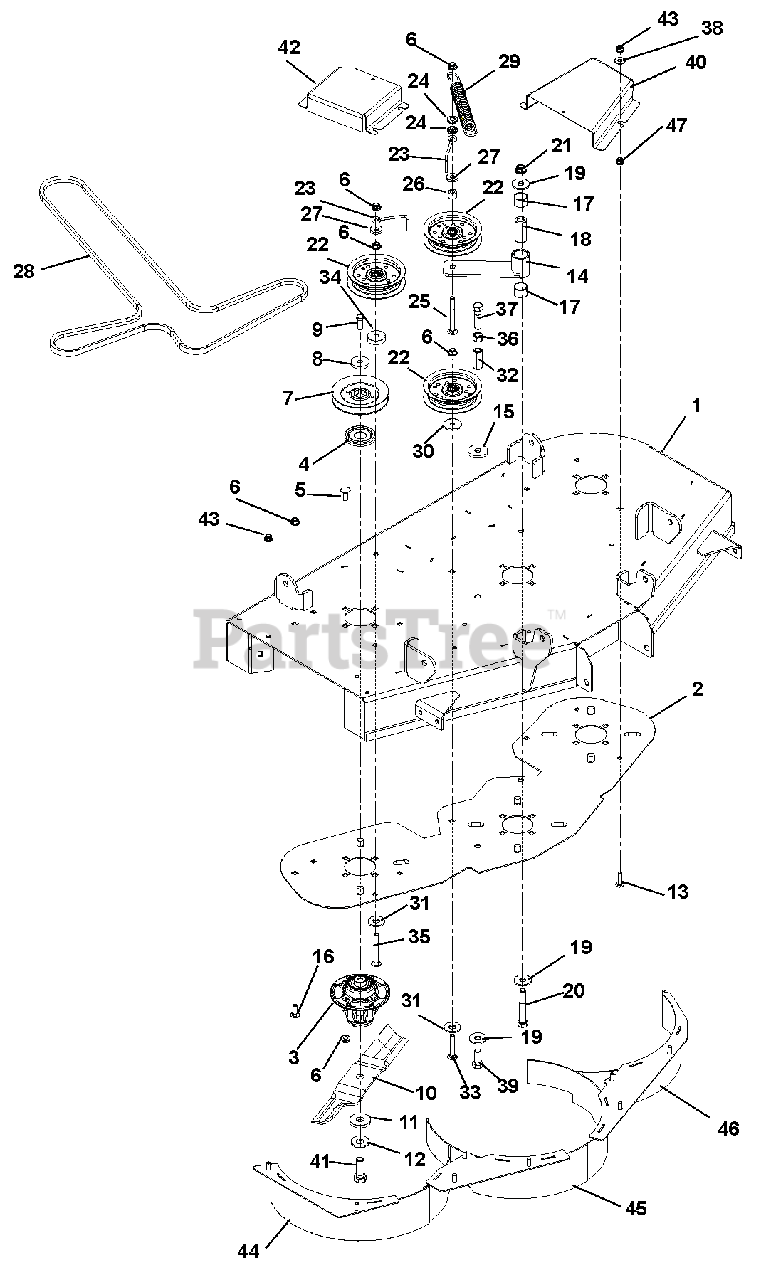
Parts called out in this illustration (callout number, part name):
1	XL-42 DECK KIT WITH DECALS
2	DOUBLER PLATE, 42 XL
3	SPINDLE ASSEMBLY
4	DUST CAP
5	@BLT-RDHDSQNK .38-16X1.25 G5YZ
5	@BLT-RDHDSQNK .38-16X1.50 G5YZ
6	@NUT-LK-NYL-FLG .38-16 YWZC
7	PULLEY, SPINDLE
8	WSHR,FLT STL.406X1.50X.245YWZC
9	BLT-HEX .38-16X1.0 GR8 YZ EP30
10	BLADE, MULCH 14.50"
11	WSHR-FLT .640X1.75X.250
12	WSHR-BLVL .669X1.535X.138
13	BLT-SERHFWH .312-18X.50 YWZC
14	WELDMENT, IDLER ARM
15	WSHR-FL-STL .515X1.625X.250 YZ
16	@BLT-RDHDSQNK .38-16X1.00 G5YZ
17	BRG, 1.00 X 1.12 X .75
18	BSHG, SPCR .502X.997X2.03 PM
19	WSHR-FL-STL.511X1.441X.125 YWZ
20	@BLT-HEX .50-13X3.50 GR5 YWZC
21	@NUT-LK-NYL-FLG .50-13 YWZC
22	ASM, IDLER 4"
23	BELT FINGER
24	BSHG-FLG .406X.88X.270X.140
25	@BLT-RDHDSQNK .38-16X3.50 G5YZ
26	BSHG-SLV .391X.688X.52 PM
27	WSHR-FL-STL .406X1.00X.188 YWZ
28	V-BELT, HA-WRAPPED
29	EXTENSION SPRING
30	WSHR-FL-STL .390X1.5X.125 YWZC
31	PLATE,IDLER MNT REINFORCEMENT
32	NUT, COUPLING 1/2-13X1.75 YWZC
33	@BLT-RDHDSQNK .38-16X2.25 G5YZ
34	SPACER, .39 X 1.50 X .380
35	@BLT-RDHDSQNK .38-16X3.50 G5YZ
36	@NUT-HEX .50-13 YWZC
37	@BLT-HEX .50-13X2.00 GR5 YWZC
38	NUT-PUSH .312
39	@BLT-HEX .50-13X1.25 GR5 YWZC
40	BELT COVER, LEFT
41	BLT-HEX .62-18X1.75 GR8 YWZC
42	BELT COVER, RIGHT
43	@NUT-LK-NYL-FLG .31-18 YWZC
44	WMT, 42 MULCH BAFFLE (RH)
45	WMT, 42 MULCH BAFFLE (CTR)
46	WMT, 42 MULCH BAFFLE (LH)
47	NUT- JAM .312-18 YWZC
